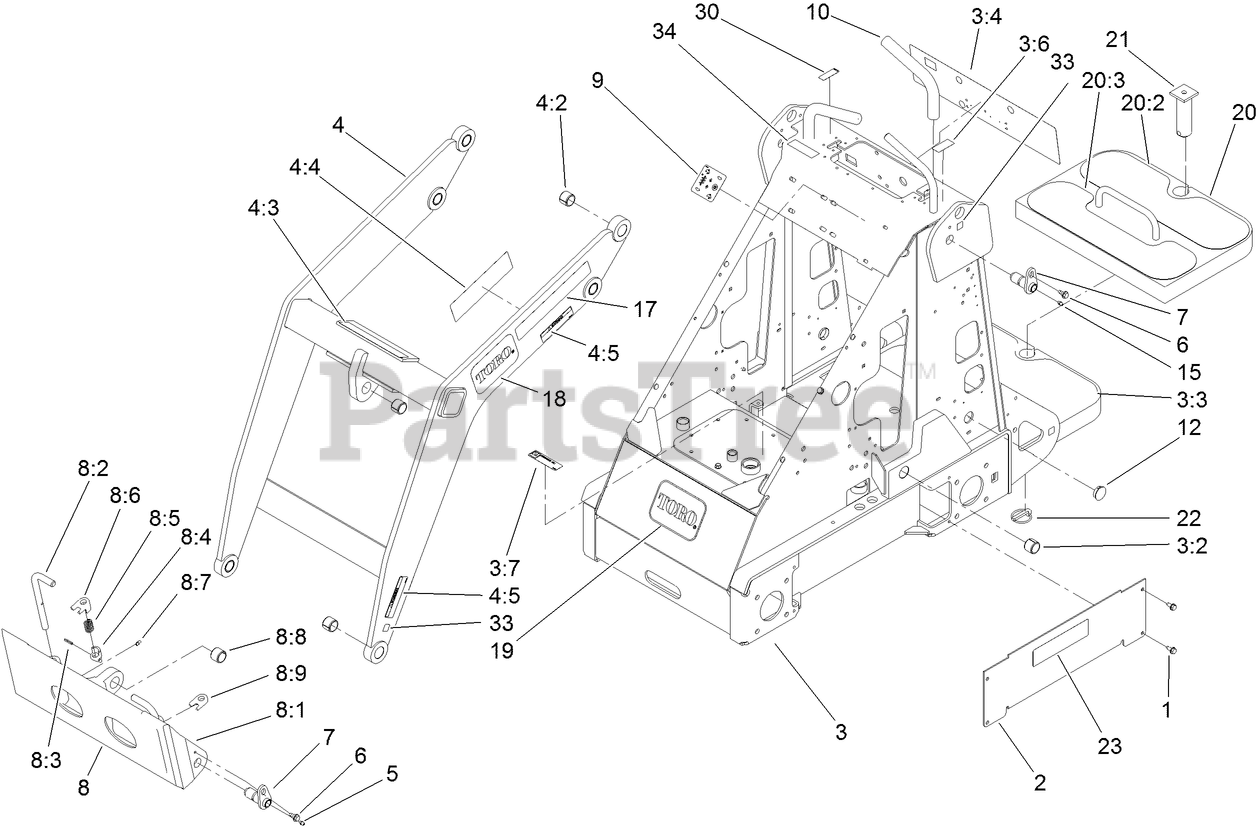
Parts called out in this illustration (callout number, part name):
1	SCREW-HWHTF
2	COVER-HOSE
3	FRAME ASM
3:2	BUSHING-TENSION
3:3	TREAD-FOOT
3:4	DECAL-PANEL, CONTROL
3:6	DECAL-THROTTLE
3:7	DECAL-OIL, HYD
4	LOADER ASM
4:2	BUSHING-TENSION
4:3	DECAL-CAUTION
4:4	DECAL-DANGER
4:5	DECAL-PINCH
5	FITTING-GREASE
6	BOLT-SHOULDER
7	PIN-PIVOT
8	QUICK ATTACH ASM
8:1	MOUNT-QTACH
8:2	PIN-LOCKING
8:3	PIN-GROOVED
8:5	SPRING-COMPRESSION
8:6	STOP-RH
8:7	FITTING-GREASE
8:8	BUSHING-TENSION
8:9	STOP-LH
9	DECAL-SELECTOR, SPEED
10	GRIP-CUSHION
12	PLUG-HOLE
15	PIN-PIVOT
18	DECAL
19	DECAL
20	COUNTERWEIGHT ASM
20:2	TREAD-FOOT
22	PIN-LYNCH
30	DECAL-CHOKE
33	DECAL-POINT, LIFT
34	DECAL-ARRESTER, SPARK
